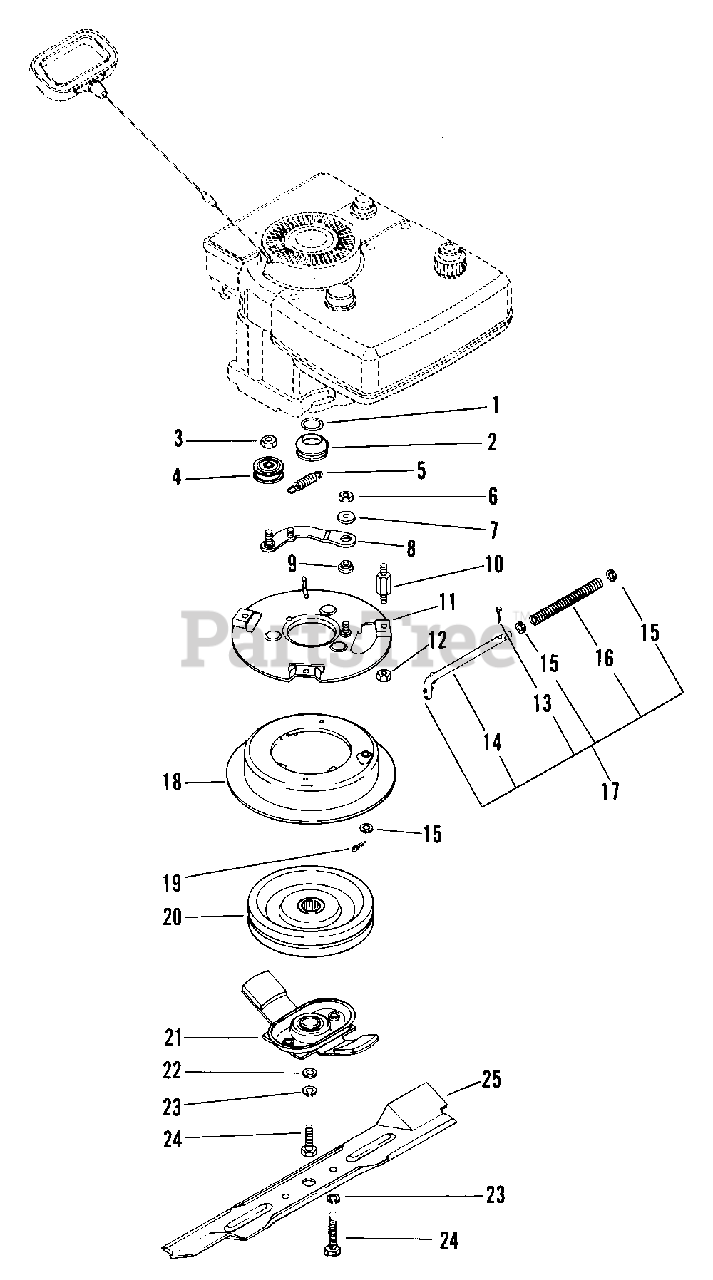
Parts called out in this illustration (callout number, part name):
1	RG-RTNG-EXT.875X.075
2	SHEAVE-BBC
3	NUT-LK-CTR .375-16 GR A PL
4	IDLER-FLAT 1.50 X .39 CLARK
5	SG-TENS .48X.44X2.0 5.0 WLD
6	NUT-LK .312-18 GR A PL
7	WSHR-FL-STL .328X1.0X.094 PL
8	IDLER ARM WELDMENT BBC
9	BSHG, FLG .325X.499X.26X.88
10	HEX STUD
11	ASM - RAMP
12	NUT-FLG. .312-18 PL
13	PIN-HAIR INT .06X.18X.77
14	ROD,RETURN BBC
15	WSHR-FL-STL .328X.555X.06 PL
16	SG-COMP .080X.550X8.50 WLD38
17	ROD RETURN ASSEM.
18	ACTUATOR,BRAKE
19	PIN-COTR .06X.50
20	BBC FLYWHEEL
21	BBC LEAF SPRING AND BEARING AS
22	WSHR-FL-STL .382X1.25X.130
23	WSHR-LK .375X.115 HVY PL
24	BLT-HEX .38-24X1.25 PL GR5
25	BLADE, 21" MOWER
